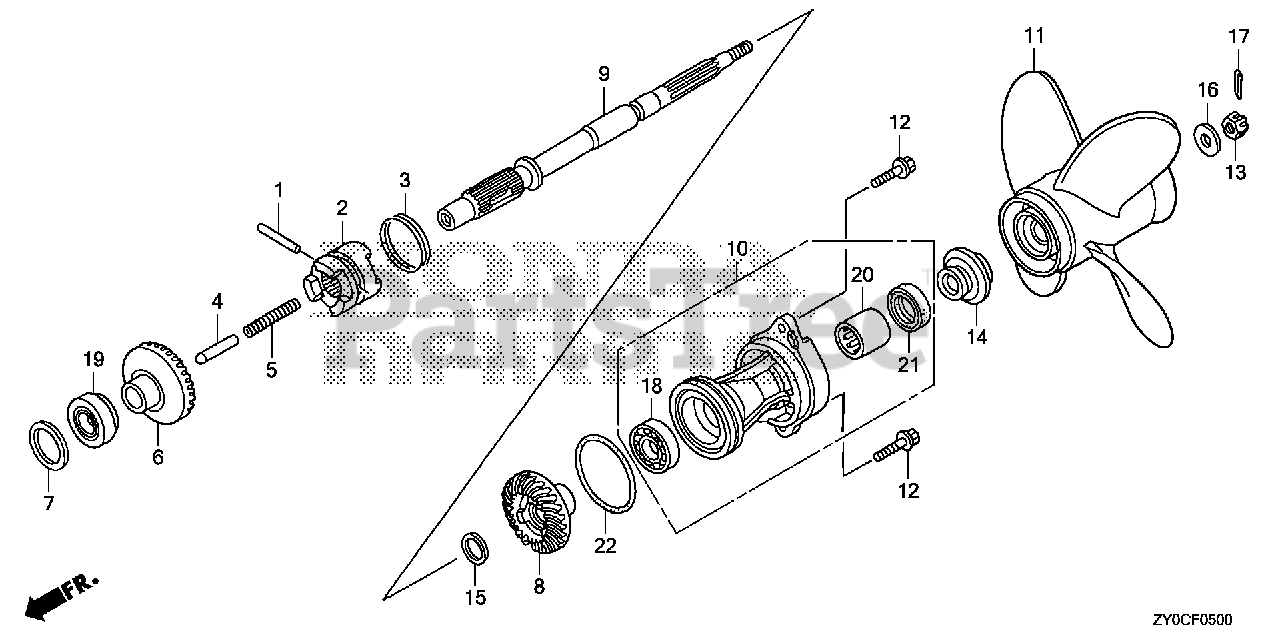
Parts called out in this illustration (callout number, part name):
1	ROLLER (4X29.8)
2	SHIFTER, CLUTCH
3	RING, CROSS PIN
4	SLIDER, SHIFT
5	SPRING, SHIFT
6	GEAR, FR. BEVEL
7	SHIM A (40MM)
7	SHIM B (40MM)
7	SHIM C (40MM)
7	SHIM D (40MM)
8	GEAR, RR. BEVEL
9	SHAFT, PROPELLER
10	HOLDER ASSY., PROPELLER SHAFT *NHB14M* (AQUA MARINE SILVER METALLIC)
11	PROPELLER, FOUR BLADES (9-1/4X7) *NH283* (STIN GRAY)
11	PROPELLER, FOUR BLADES (9-1/4X8) *NH283* (STIN GRAY)
11	PROPELLER, FOUR BLADES (9-1/4X9) *NH283* (STIN GRAY)
11	PROPELLER, FOUR BLADES (9-1/4X10) *NH283* (STIN GRAY)
11	PROPELLER, FOUR BLADES (10X7-5/8) *NH283* (STIN GRAY)
12	BOLT, FLANGE (6X20)
13	NUT, CASTLE (10MM)
14	WASHER, PROPELLER THRUST
15	WASHER (18MM)
16	WASHER (10MM)
17	PIN, SPLIT (3MM)
18	BEARING, RADIAL BALL (25X47X12)
19	BEARING (25X47X15)
20	BEARING, NEEDLE (17X24X20) (NTN)
21	SEAL, WATER (17MM)
22	O-RING (59.4X3.1)
